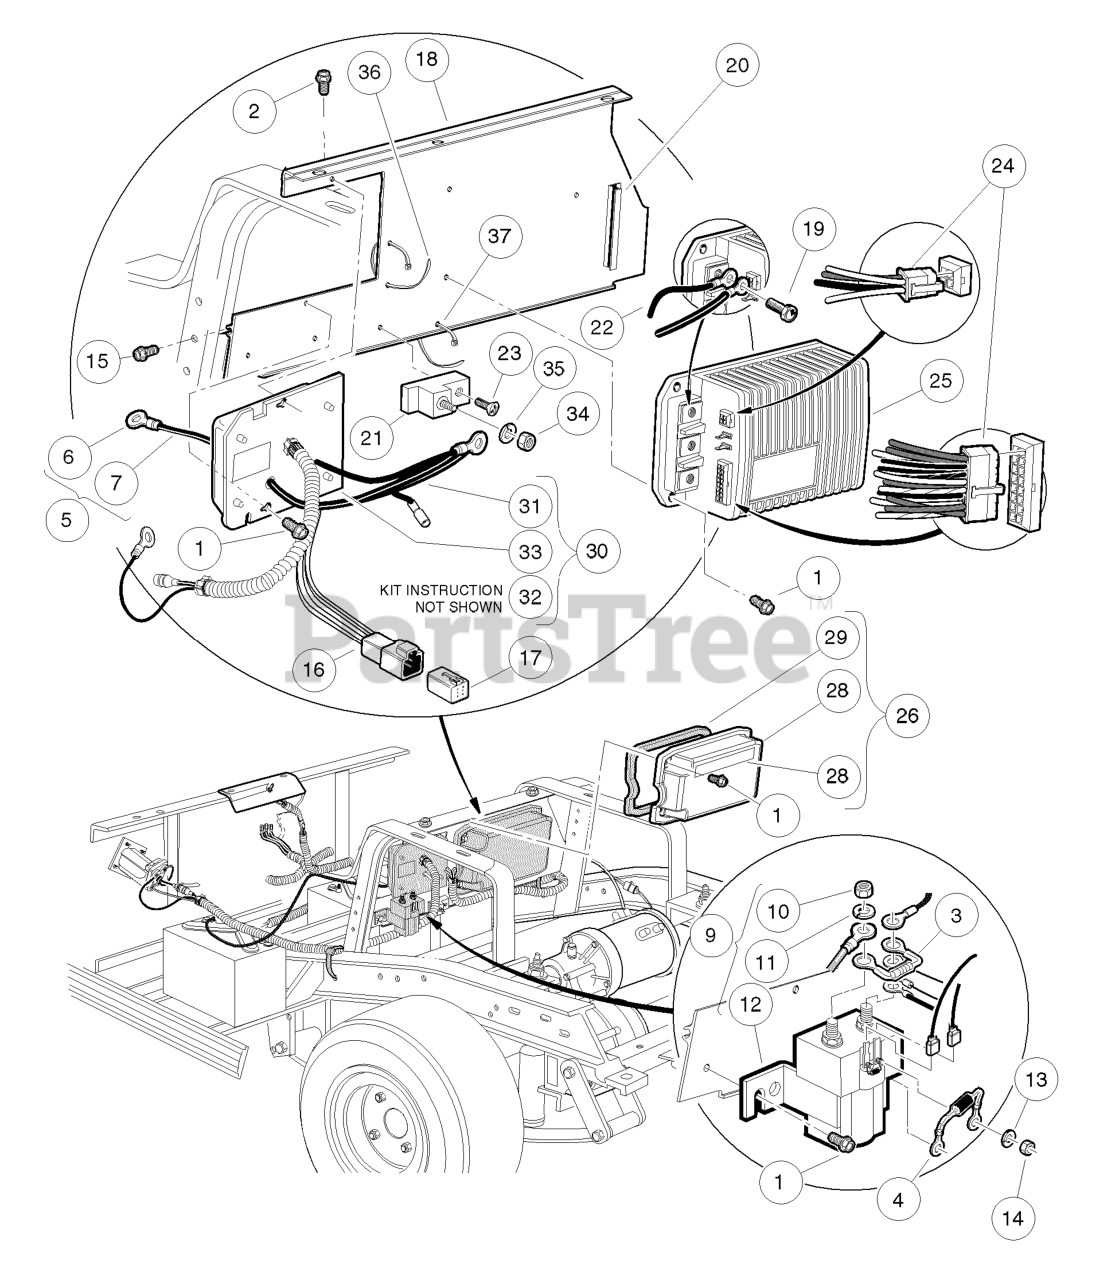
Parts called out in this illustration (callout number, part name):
1	SCREW HX TYP TT
3	RESISTOR ASSEMBLY
4	ASM, DIODE
5	GROUND WIRE KIT 48V
6	Compression Lug
7	Wire Assembly, Black
8	TIE WRAP, 8" NYLON
9	SOLENOID, 48V W/ CONTACT STUD
10	NUT, M8-1.25 HEX
13	Washer, Lock
14	Nut
15	SCREW, 5/16-18 X 1.25 THRD FRM
16	KIT 6-PINRECEPT AND WEDGE LOCK
17	KIT 6-PIN PLUG AND WEDGE LOCK
18	PLATE, COMPONENT COMMON
19	BOLT IQ CONTROLLER TERMINAL
20	Extrusion, Cover Support
21	TERMINAL BLOCK
22	WIRE ASSY #10 BLACK
23	SCREW 10-24X.75 PHIL THD-F
24	KIT CONNECTOR IQ CONTROLLER
25	ONTROLLER, 48V IQ GOLF
26	COVER ASM - CONTROLLER
27	DECAL, COMPONENT COVER
28	COVER - CONTROLLER, DEEP
29	GASKET - CONTROLLER COVER
30	KIT OBC
31	Asm Wire #10blk Ground
32	Instr Obc Ds Pre 01-28-2007
34	NUT, 5/16-18 HEX
35	LOCKWASHER, 5/16 SPLIT
36	TIE WRAP , 11" NYLON
37	TIE WRAP, 8" NYLON
